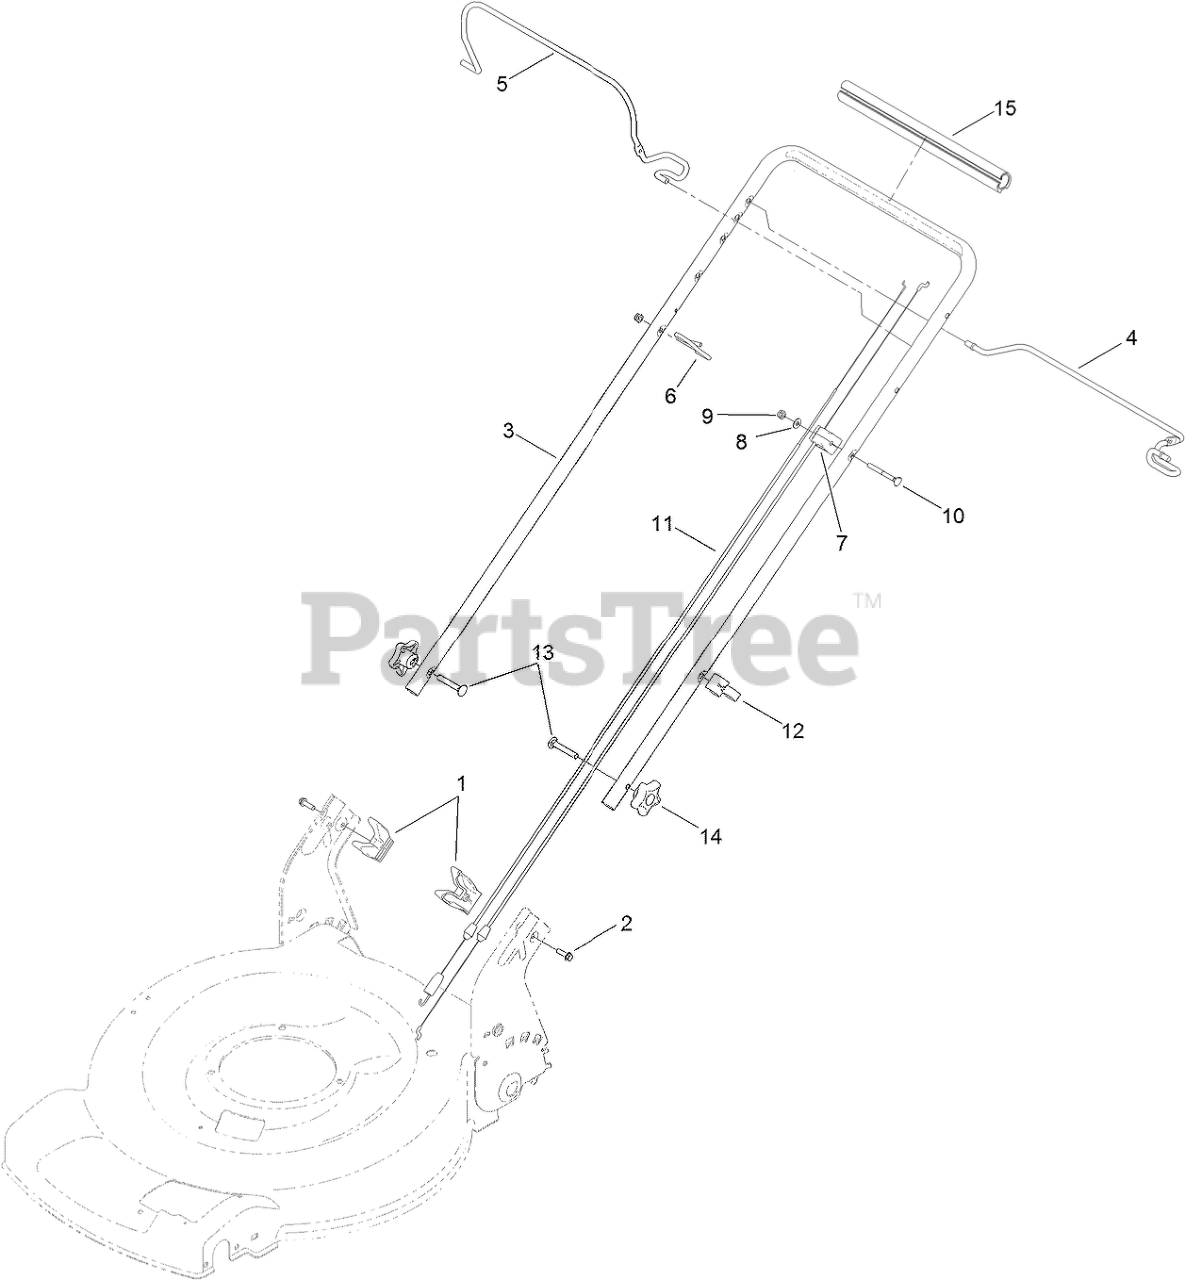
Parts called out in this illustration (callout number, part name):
1	ANCHOR-BAG
2	SCREW-HWH
4	BAIL-TRACTION
5	BAIL-BRAKE
6	GUIDE-ROPE
7	CABLE-BRAKE
8	WASHER-FLAT
9	NUT-LOCK, NI
10	SCREW-HANDLE
11	CABLE-TRACTION
12	GUIDE-CABLE
13	Screw-CARR
14	KNOB-HANDLE
15	GRIP-HANDLE, COMFORT
